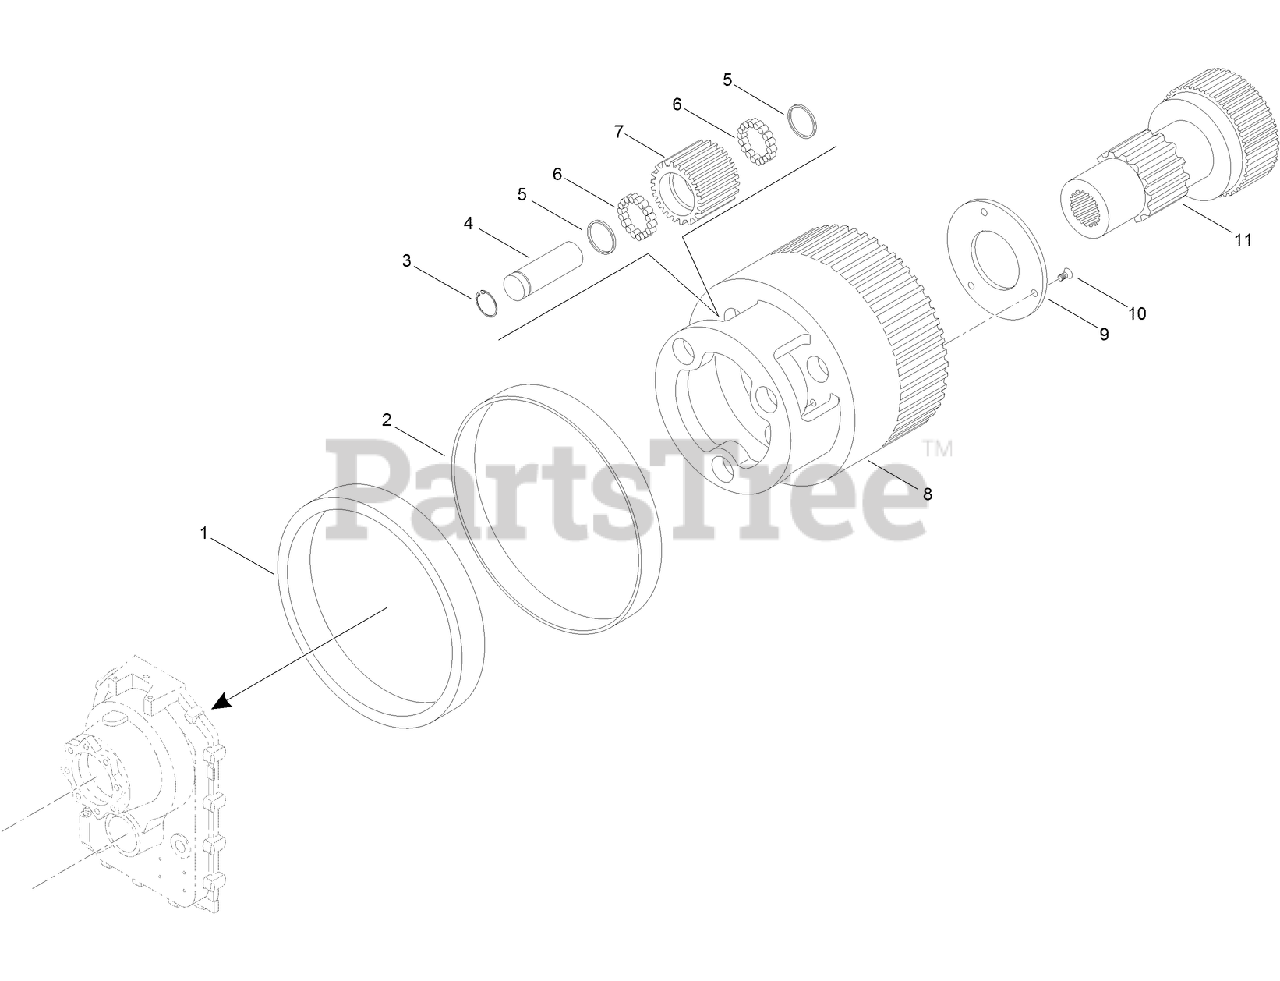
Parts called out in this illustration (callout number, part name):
1	BUSHING
2	BUSHING
3	RING-RETAINING, INT
4	PIN-CARRIER
6	BEARING-NEEDLE
7	GEAR-PLANETARY
8	GEAR-HUB, PLANETARY
9	WASHER-THRUST
11	SHAFT-SUN GEAR, 30T
